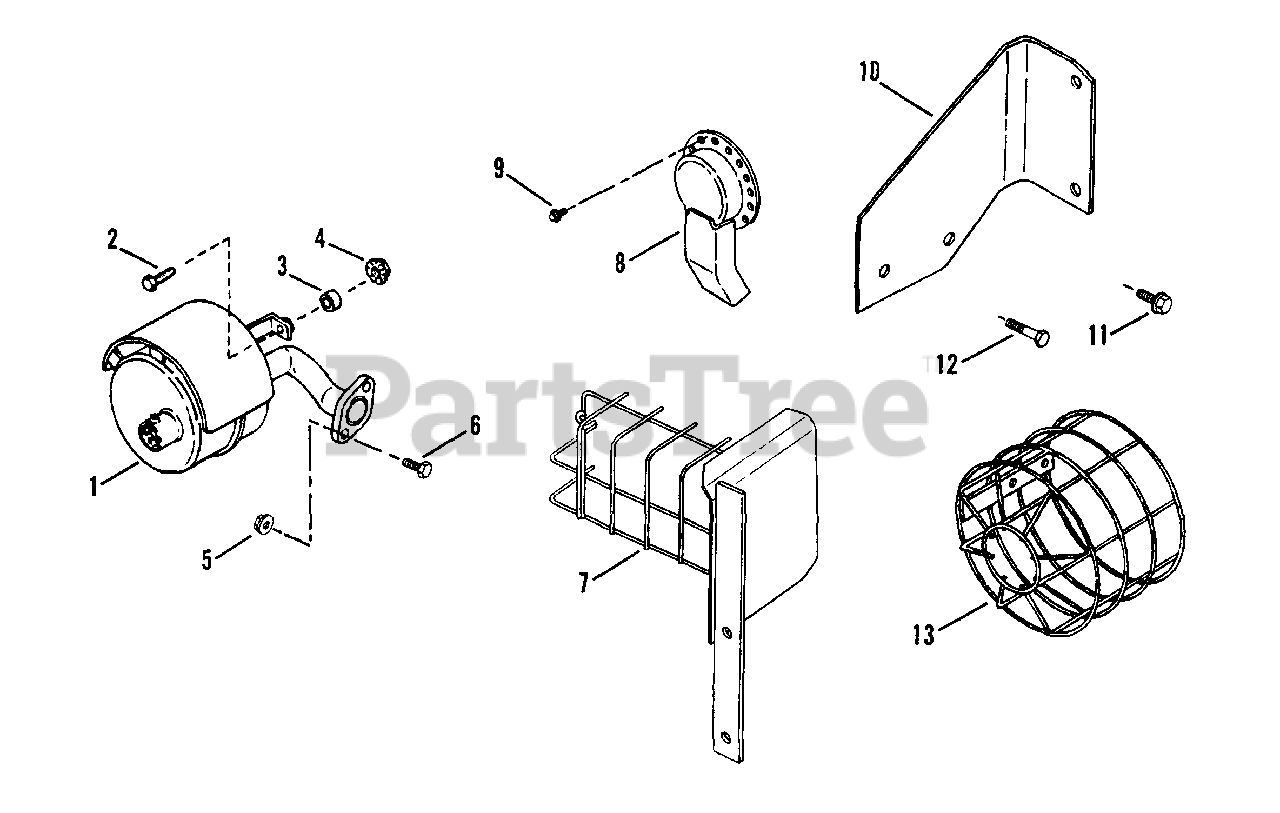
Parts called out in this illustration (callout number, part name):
1	MUFFLER
2	SCREW, 1/4-20 x 3/4" Hex Head Cap
3	SPACER
4	NUT, 1/4-20 Hex Flange Lock
5	NUT, 5/16-18 Hex Flange Lock
6	SCREW, 5/16-18 x 3/4" Hex Head Cap
7	GUARD, Muffler
8	DEFLECTOR, Heat
9	SCREW, #8-18 x 1/2" Self-Tapping
10	BRACKET, Muffler Guard
11	SCREW, 1/4-20 x 5/8" Hex Head, Self-Tapping
12	SCREW, 1/4-20 x 1" Hex Head Cap, Grade 5
13	GUARD, Muffler
